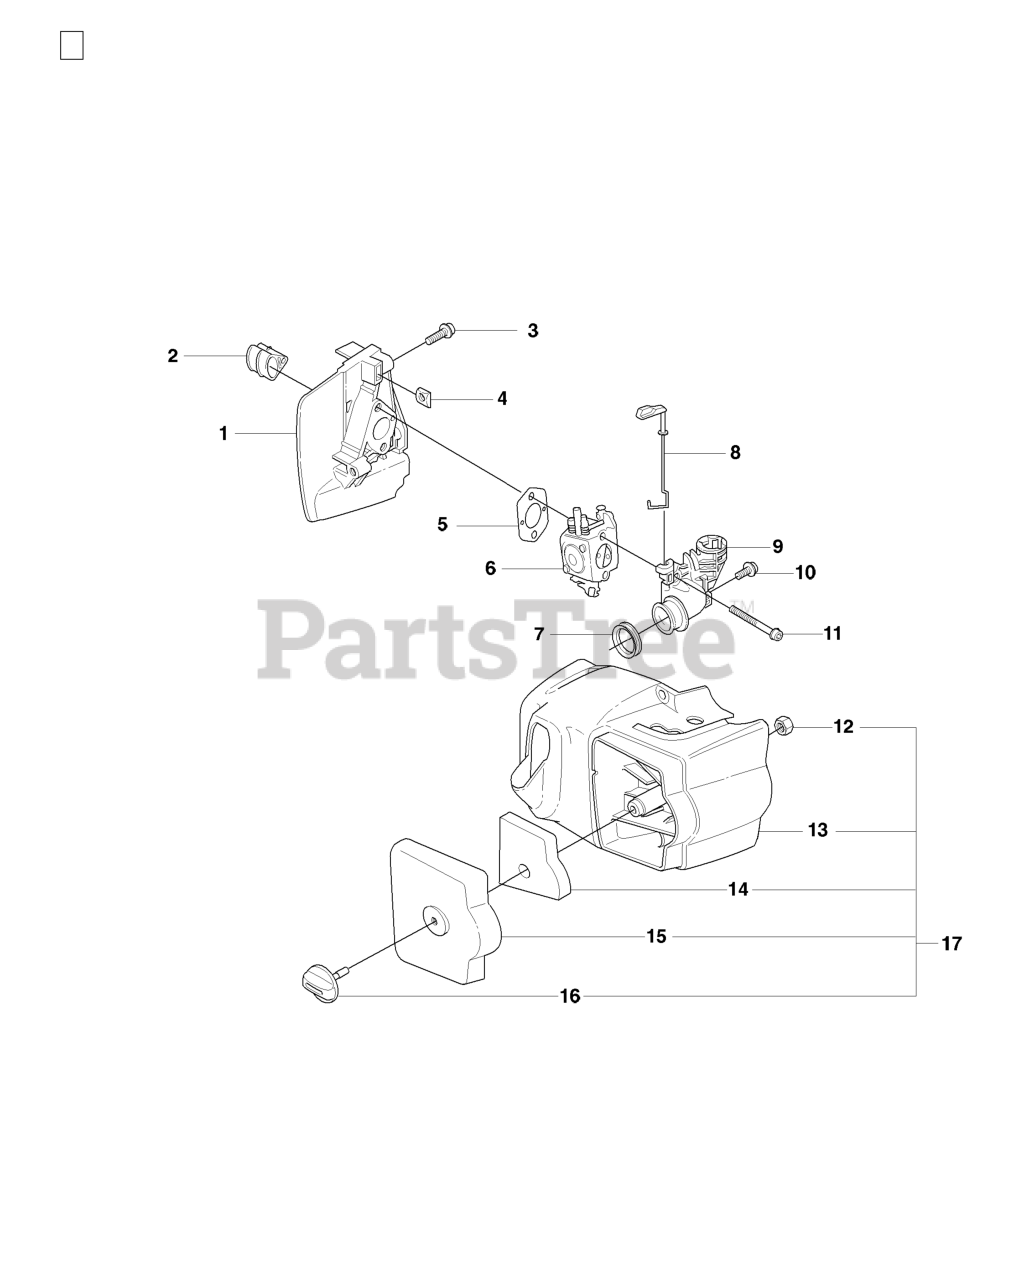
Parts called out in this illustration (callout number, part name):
3	SCREW
6	CARBURETOR
8	CHOKE CONTROL
14	AIR FILTER
15	AIR FILTER COVER
17	CYLINDER COVER ASSY 325
